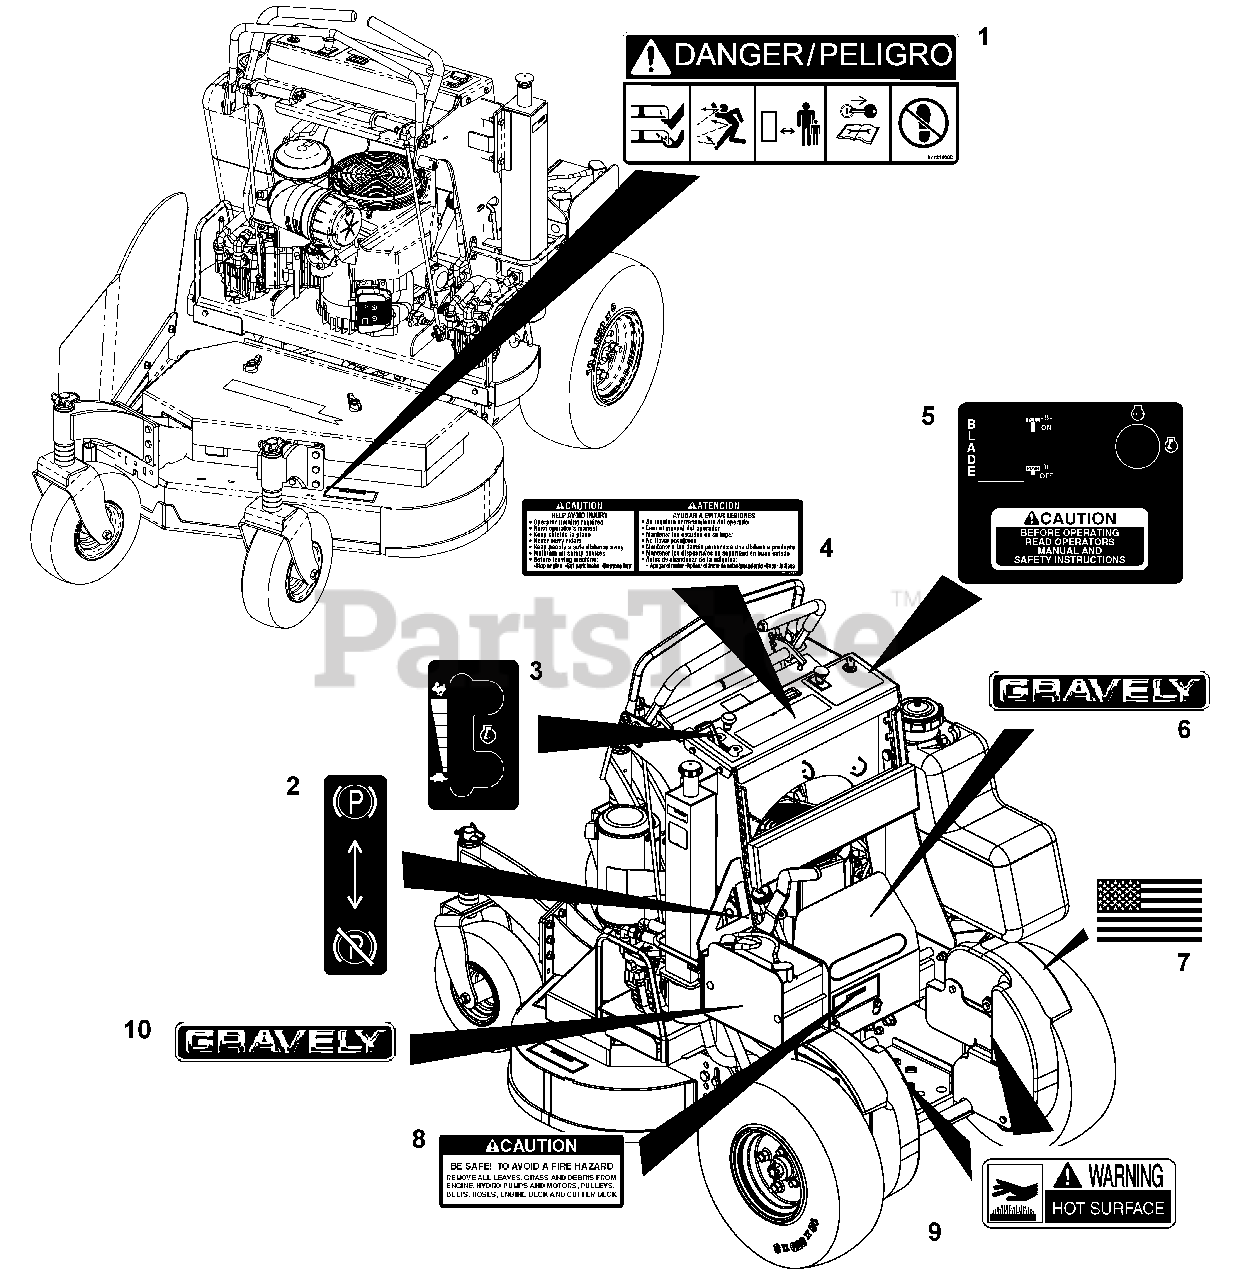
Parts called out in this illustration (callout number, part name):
1	Decal, Danger - Blade Contact
2	Decal, Park Brake
3	Decal, Throttle
4	Decal, General Caution
5	Decal, PTO/Ignition
6	Decal, 15" Gravely Logo
7	Decal, American Flag
8	Decal, Caution - Fire Hazard
9	Decal, Warning, Hot Surface
10	Decal, Gravely Logo
